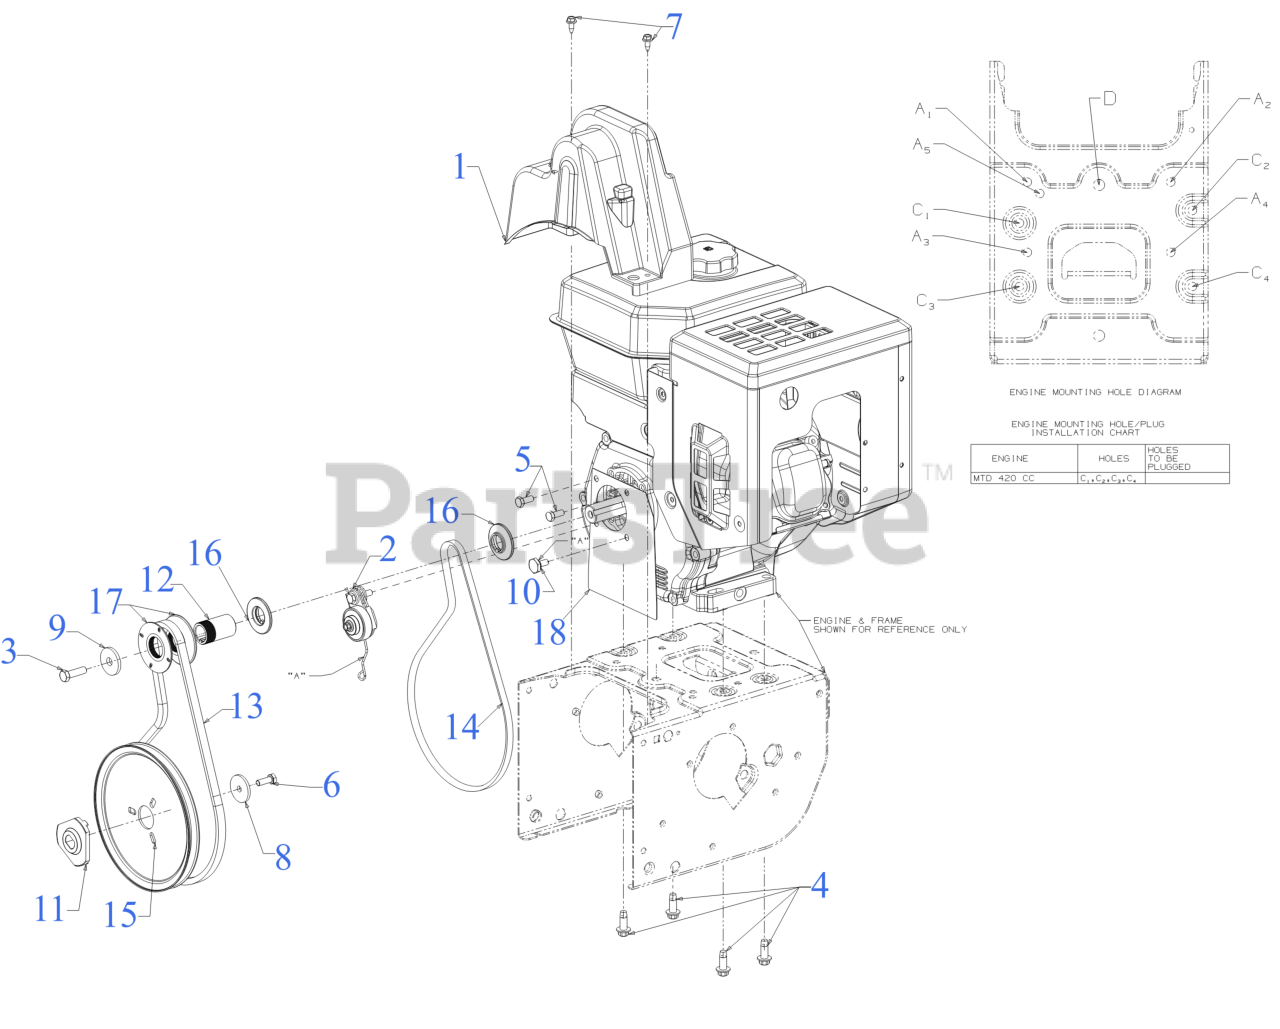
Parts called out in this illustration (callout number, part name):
1	BELT COVER SERVICE KIT (631-05323)
1	BELT KEEPER COVER BRACKET
1	HEX SCREW #12-16 x .50
2	IDLER ASSEMBLY
3	SCREW 3/8-24X1.25
4	SCREW 3/8-16 x 1
5	SCREW 5/16-24 x .750 GR5
6	SCREW 5/16-24 x .875 GR5
7	SCREW 1/4-20X.625
8	FLAT WASHER
9	FLAT WASHER .45 x 1.5 x .172 HT
10	SHOULDER SCREW
11	ADAPTER PULLEY .75 DIA W/DD
12	PULLEY SPACER
13	BELT-.500 x 37.00
14	V-BELT 3/8 x 35.68"
15	AUGER PULLEY
16	HALF PULLEY-3/8 V x 1.7160
17	HALF PULLEY A2.76 x 1.140 SPLINE
18	ENGINE PLATE (FRONT COVER)
